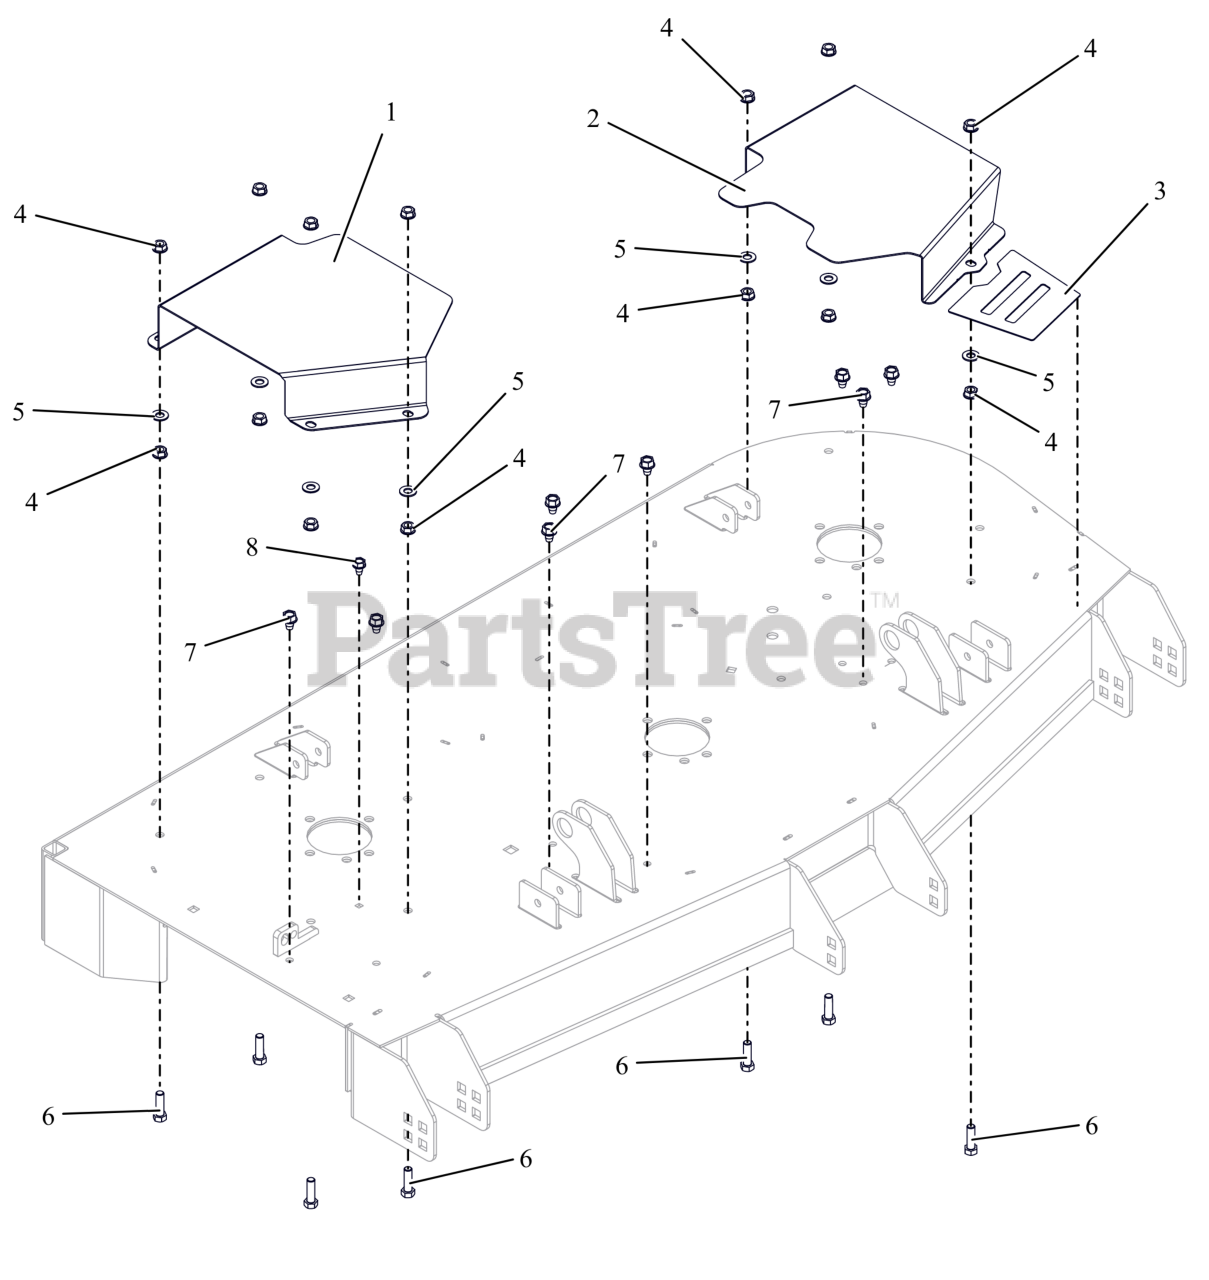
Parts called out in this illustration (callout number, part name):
1	COVER, BELT 52" & 60" RIGHT
2	COVER, BELT 52" LEFT (ORANGE)
3	GRIP TAPE 52-60 BELT COVER
4	NUT, SPNLK-FLG .38-16 G5 ZCC
5	WSHR,FLT .406X.812X.065 ZCC
6	BLT, HEX .38-16X1.25 G5 ZCC
7	SCR,TAP .375-16X.50 HWH TR ZCC
8	SCR,TAP .312-18X.50 HWH TR ZCC
